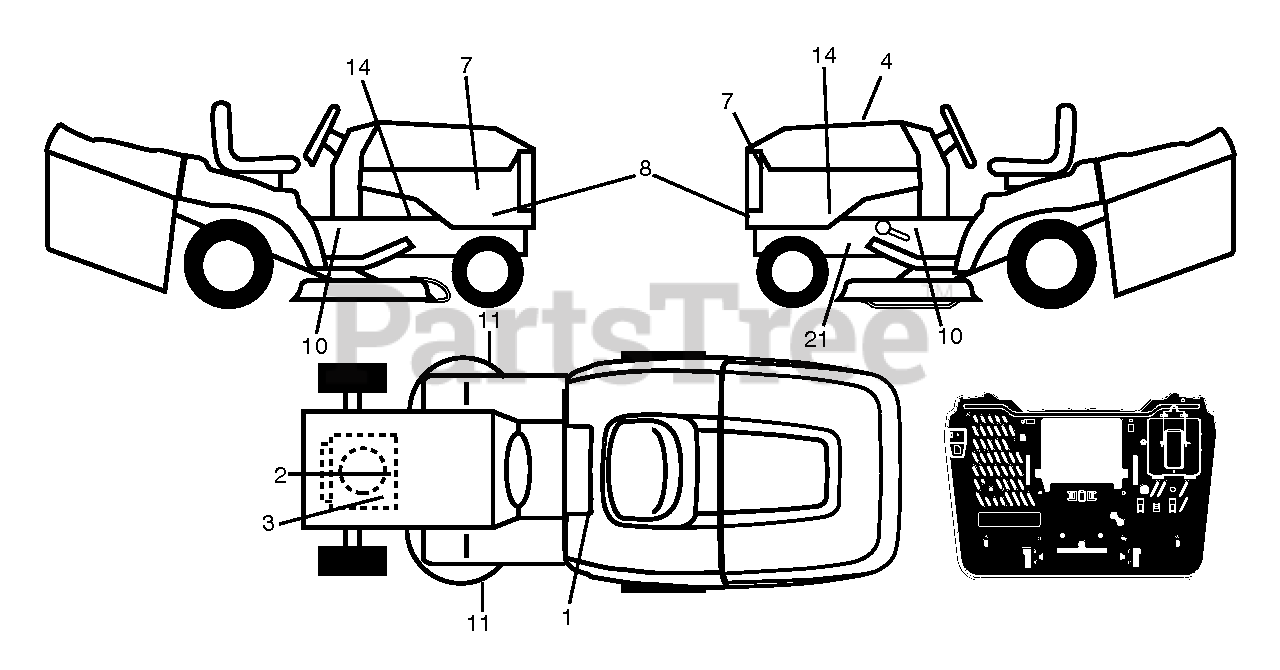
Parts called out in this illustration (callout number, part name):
1	DECAL.WARNING.COMBINED.T/CRD
2	DECAL.ENGINE.WARNING
3	DECAL.ENG.BS.656CC.HS.382274
4	DECAL.RPL.BSM40.HS.TCRD.107K46
7	DECAL.BADGE.170MM.TEXTLOGO.
8	Decal, Side Panel HUSQGT TC
10	DECAL.WARNING.SERVCE/FIRE
11	DECAL.CUTFINGER.CE.02
14	DECAL.CHASSIS.HOT.MUFFLER
21	DECAL DECAL V-BELT 97 CM CRD
